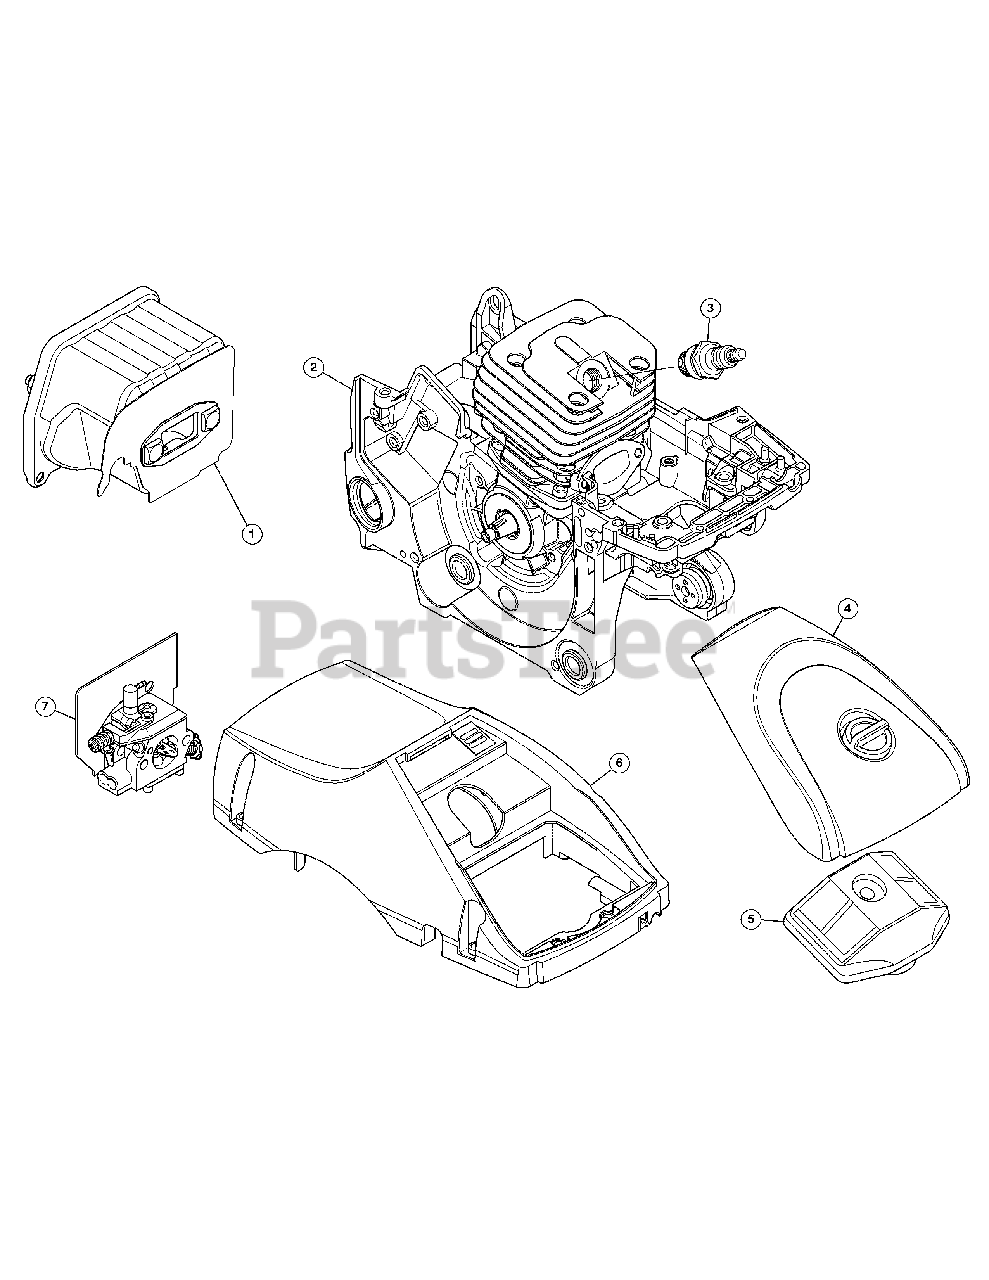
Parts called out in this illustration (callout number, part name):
1	Muffler Assembly
2	46cc Short Block Assembly
3	Spark Plug
4	Air Filter Cover Assembly
5	Air Filter
6	Cylinder Cover Assembly (with Plate and Screws (5))
7	Carburetor Assembly
